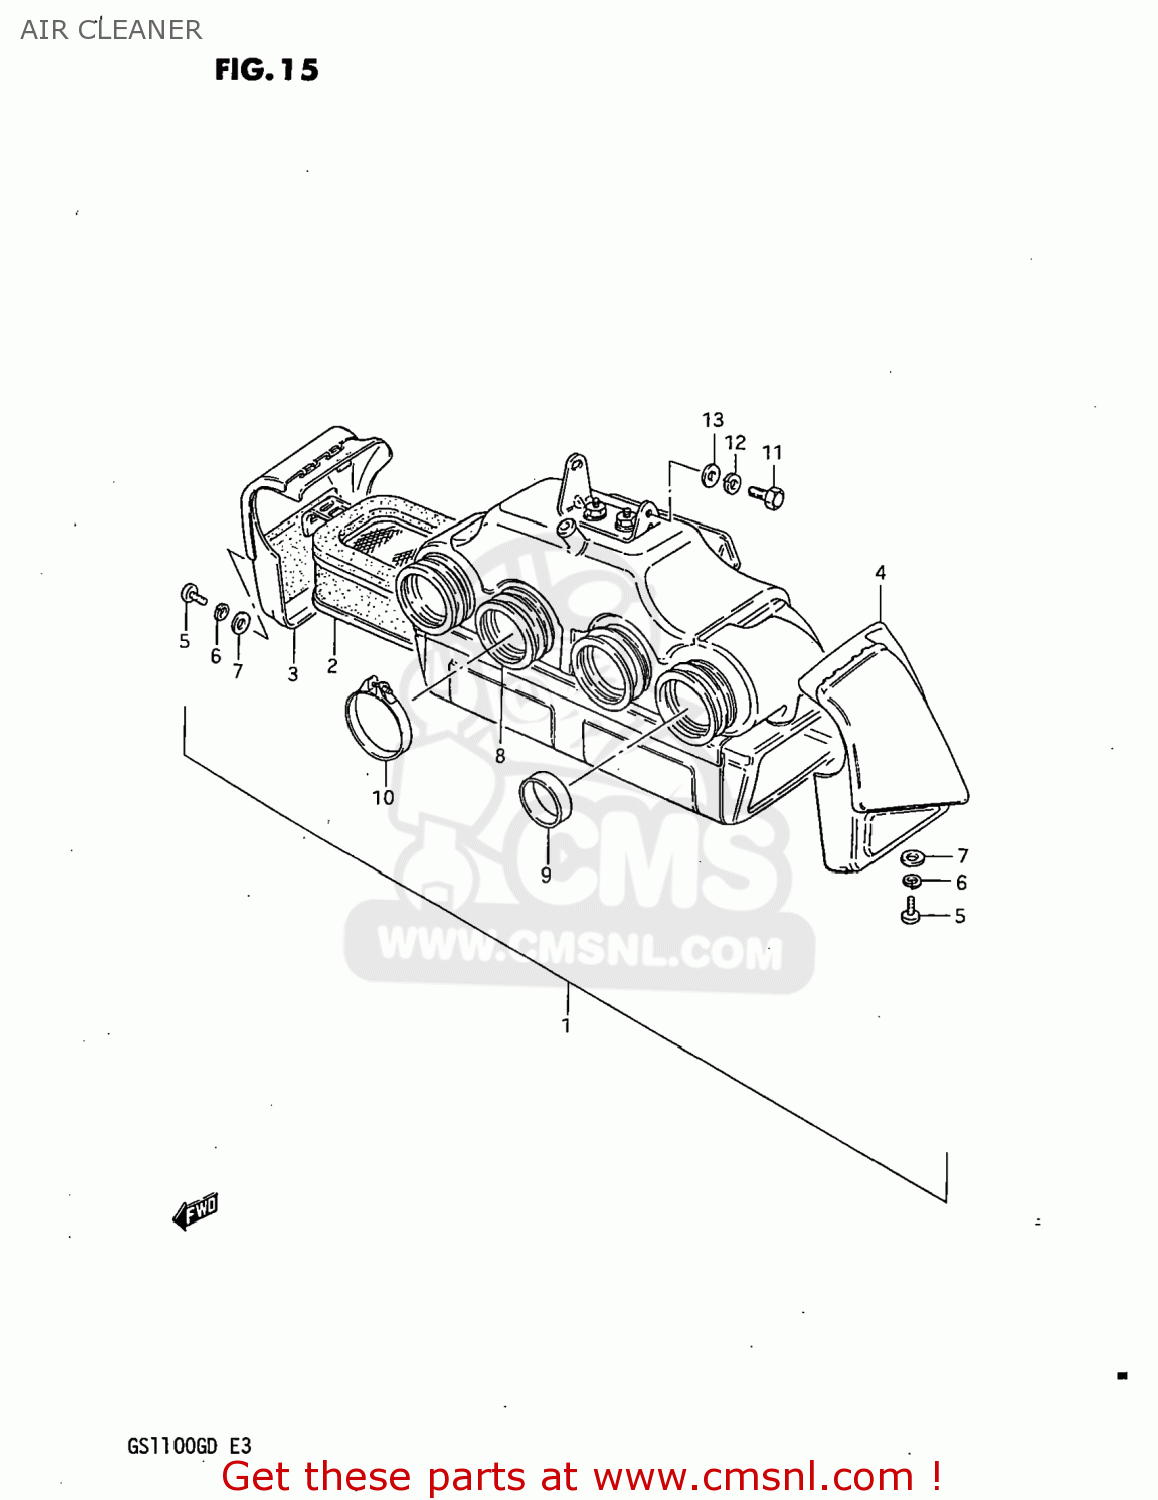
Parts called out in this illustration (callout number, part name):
1	CLEANER ASSEMBLY,AIR
2	FILTER ASSY
3	CAP,AIR CLEANER
4	CAP,AIR CLEANER
5	SCREW
6	LOCK WASHER
7	WASHER
8	TUBE,OUTLET
9	RING,CARBURETOR AIR IN
10	CLAMP
11	BOLT
12	LOCK WASHER
13	WASHER 6MM
